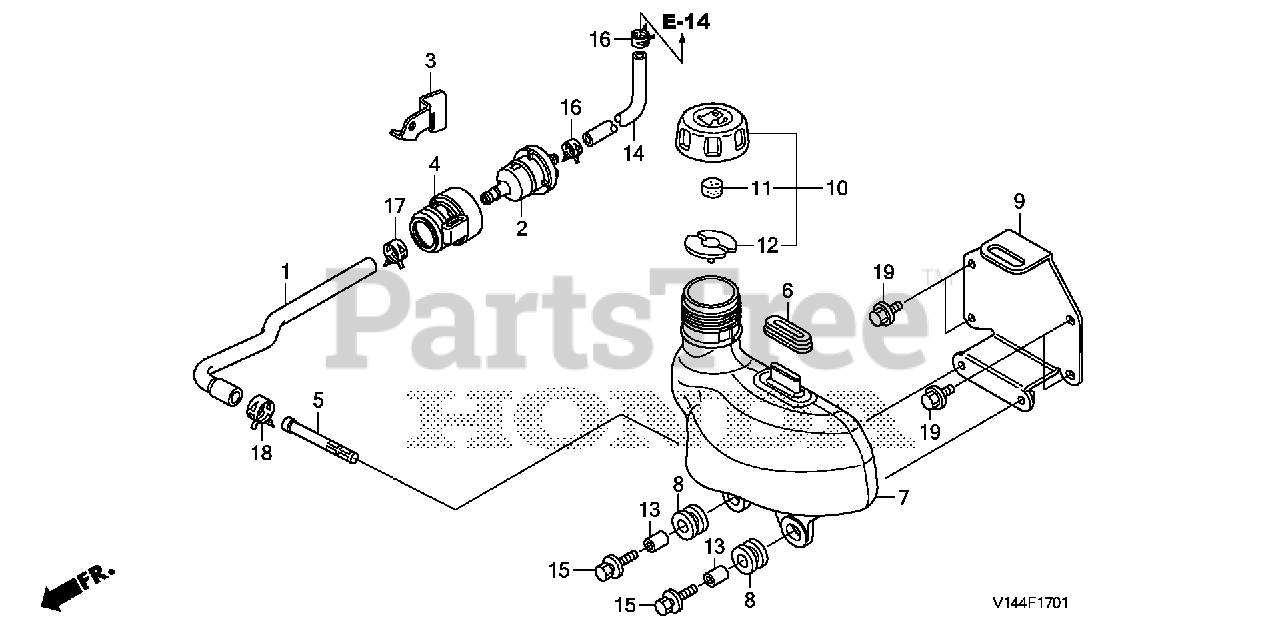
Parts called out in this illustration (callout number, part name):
1	TUBE A, FUEL (FKM)
2	FILTER, FUEL
3	STAY, FUEL STRAINER
4	SUSPENSION, STRAINER
5	BUSH, FUEL PURGE
6	RUBBER, TANK SETTING
7	TANK, FUEL (COO)
8	RUBBER B, TANK MOUNTING
9	BRACKET, FUEL TANK
10	CAP ASSY., FUEL TANK
11	SPONGE, FUEL CAP BREATHER
12	GASKET, FUEL CAP
13	COLLAR (14X6.1)
14	TUBE, FUEL (4.5X95) (FKM)
15	BOLT-WASHER (6X25)
16	CLAMP, TUBE (D8)
17	CLAMP, TUBE (D10)
18	CLAMP, TUBE (D12)
19	BOLT, FLANGE (6X12)
